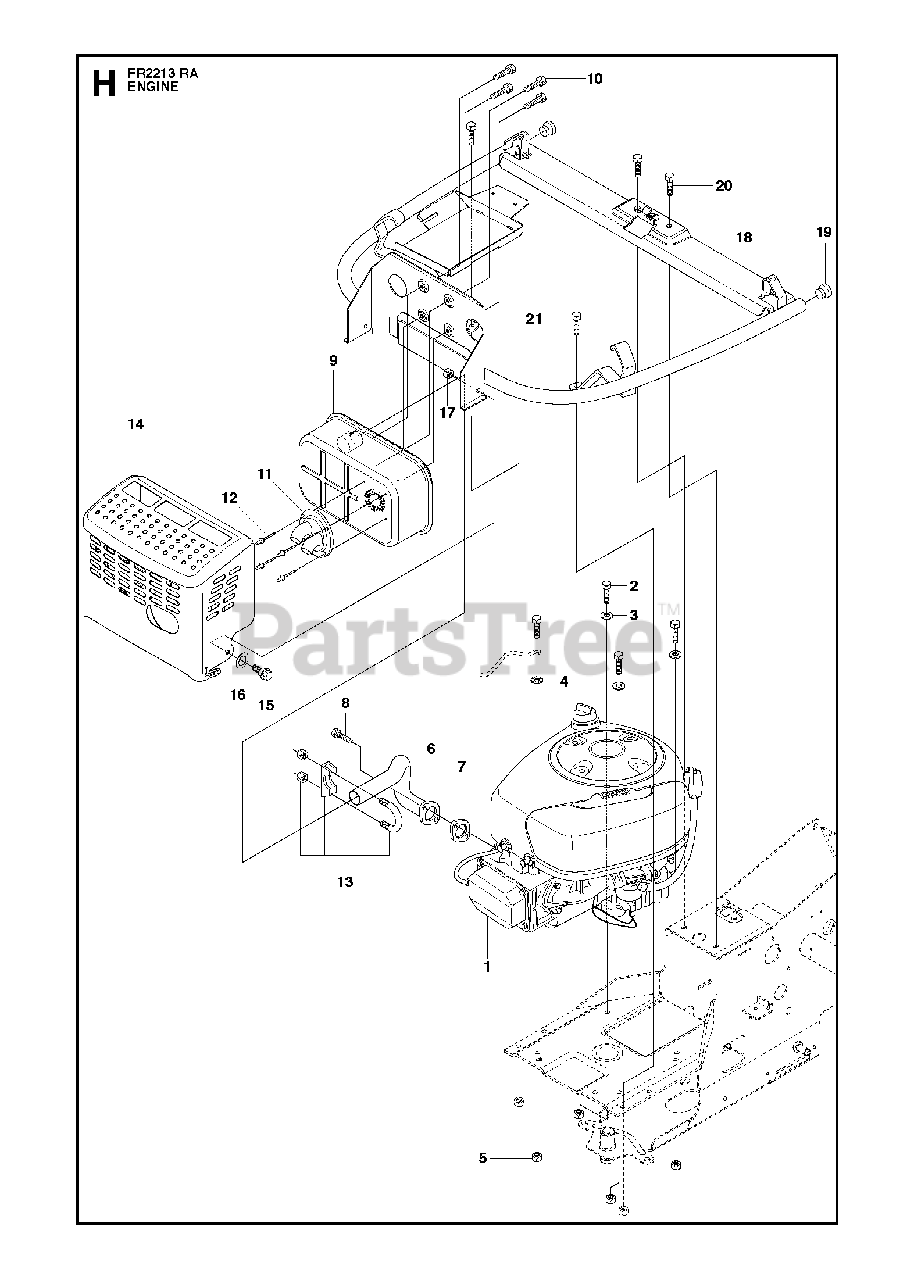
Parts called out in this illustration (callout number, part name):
3	WASHER BRB 8.4X17
5	LOCKNUT M8
9	MUFFLER
16	SPRINGWASHER
17	LOCKNUT M8
